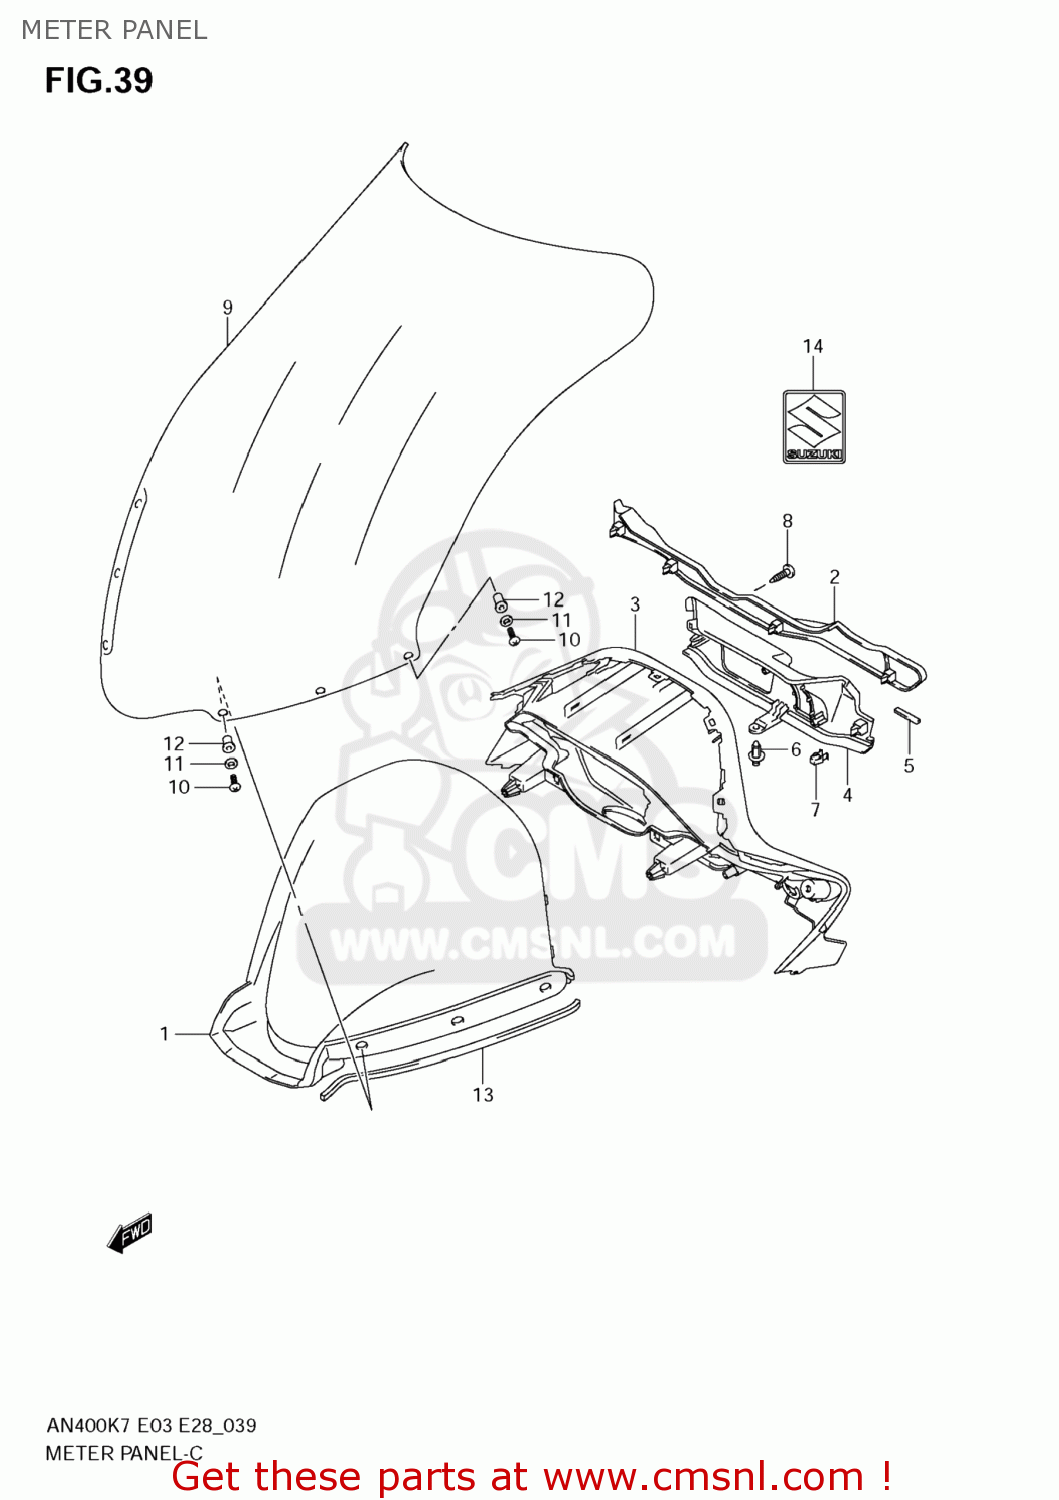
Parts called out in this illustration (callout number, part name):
1	PANEL,METER FR
2	PANEL,METER UPR
3	PANEL,METER RR
4	PANEL,FR
5	TAPE(6X25X0.13)
6	CLIP(BLACK)
7	CLIP
8	SCREW
9	WINDSCREEN
10	SCREW
11	WASHER
12	NUT
13	CUSHION
14	EMBLEM,S
